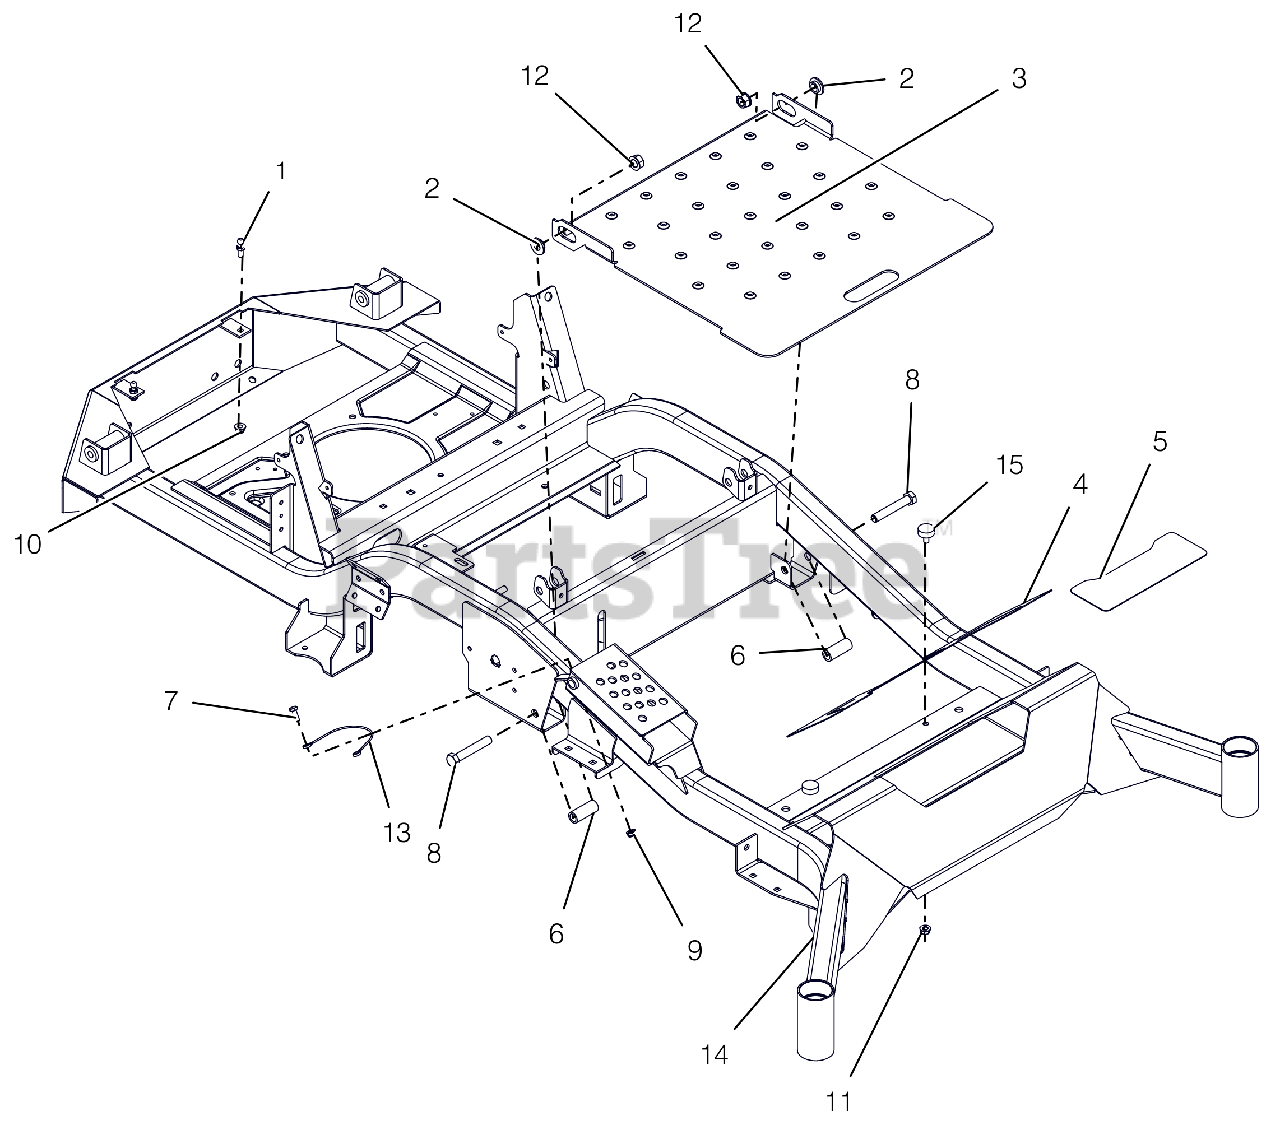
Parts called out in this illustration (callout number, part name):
1	STUD- BALL
2	BSHG-FLG .515X.750X.395X1.120
3	PLATE, ACCESS
4	GRIP, FRONT
5	GRIP, STEP
6	SPACER, .515X.75X1.83
7	@BLT-HEX .25-20X.75 GR5 YWZC
8	@BLT-HEX .50-13X3.00 GR5 YWZC
9	@NUT-LK-NYL-FLG .25-20 YWZC
10	NUT,LK-NYL-FLG .31-18 G5ZC120
11	@NUT-SPNLK-FLG .312-18 YWZC
12	@NUT-LK-TOP-FLG .50-13 YWZC
13	CABLE, 12.0 LANYARD, NYLON
14	APEX 60"FRAME W/SAFTETY DECALS
15	BUMPER, RUBBER
